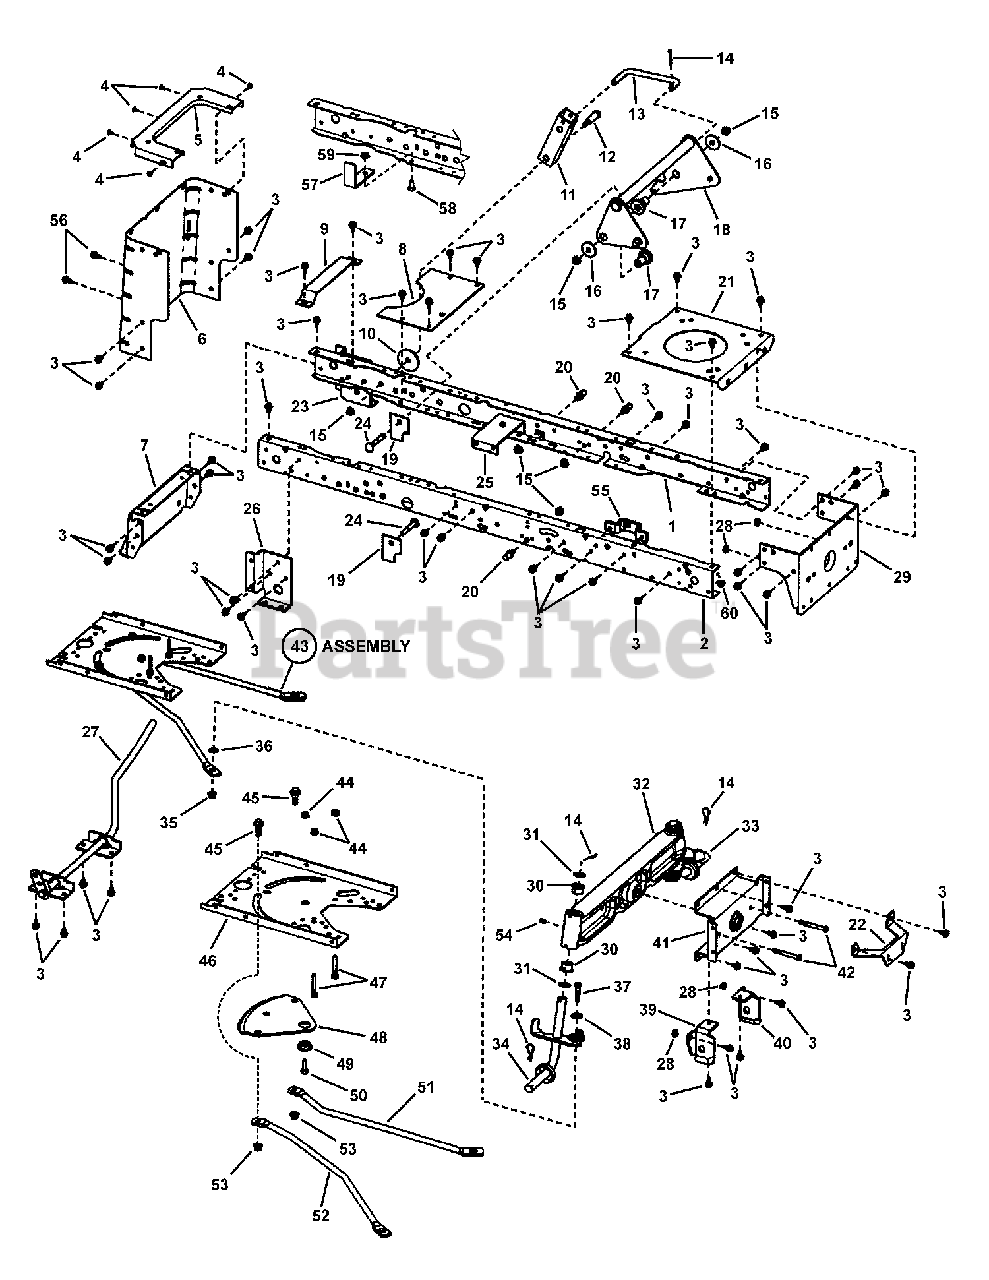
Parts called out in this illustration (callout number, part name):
1	RAIL, Frame LH
2	RAIL, Frame RH
3	CAPSCREW, 5/16-18 Hex Washer Face
4	SCREW, #10-24 x 1/2" Hex Washer Self-Tap SEMS
5	TOP, Rear Plate
6	PLATE, Rear
7	PLATE, Hitch
8	PLATE, Idler Pulley Hydro Gear
9	BRACKET, Battery Support
10	WASHER, .406 x 2.25 Plain
11	BRACKET, Pivot
12	BOLT, 3/8-16 x 1.563 Shoulder
13	LINK, Handle Lift
14	PIN, 1/8 x 1-1/4" Cotter, YZ
15	NUT, 3/8-16 Hex Flange Lock, YZ
16	WASHER, .391 ID x 1-1/4" OD
17	SPACER - Lifter Pivot
18	WELDMENT, Lifter
19	PLATE, Stiffening
20	PIN - Threaded Shoulder (3/8-16)
21	PLATE, Engine
22	BRACKET, Muffler Mounting
23	BRACKET, Transaxle LH
24	BOLT, 3/8-16 x 2-1/2" Round Head Short Square Neck
25	ASSY, Idler Brkt (Secondary)
26	BRACKET, Transaxle RH
27	WELDMENT - Brake Lever
28	NUT, 5/16-24 Hex Flange Lock, BZ
29	BRACKET, Hanger Rear
30	BEARING SPINDLE
31	WASHER, .77 x 1.13 x .06
32	GT AXLE - Cast Iron
33	WELDMENT - Spindle LH
34	WELDMENT - Spindle RH
35	NUT, 3/8-16 Hex Flange, NC
36	FLAT WASHER, .41 x .82 x 16 GA
37	BOLT, 3/8-16 x 1-1/2" Hex, GR 5
38	FLAT WASHER, 25/64 ID x 1" OD x 14 GA.
39	HANGER, Deck RH
40	HANGER, Deck LH
41	HANGER, Axle
42	BOLT, 5/16-24 x 2-3/4" Hex Head
43	ASSY, Sector Gear (Gear Drive - LT)
44	NUT, 5/16-18 Hex Flange Lock, BZ
45	BOLT, 3/8-16 Shoulder
46	PLATE, Steering Mount
47	SCREW - Guide (5/16-18)
48	GEAR - Sector
49	BEARING - Sector Gear
50	SCREW, 5/16-18 x 1" Hex Head Cap, GR 5, YZ
51	DRAG LINK, LH
52	DRAG LINK, RH
53	NUT, 3/8-16 Hex Flange Lock, YZ
54	FITTING - Lubrication (1/4-28 Self-Tap)
55	BRACKET, Bellcrank
56	SCREW, 3/8-16 x 3/4 Hex Washer Self-Tap
57	GUIDE, Hydro Belt
58	BOLT, 5/16-18 x 5/8 Hex Head, GR 5
59	NUT, 5/16-18 Hex Flange Center Lock
60	NUT, 5/16-18 Hex Flange Lock, GR 5
